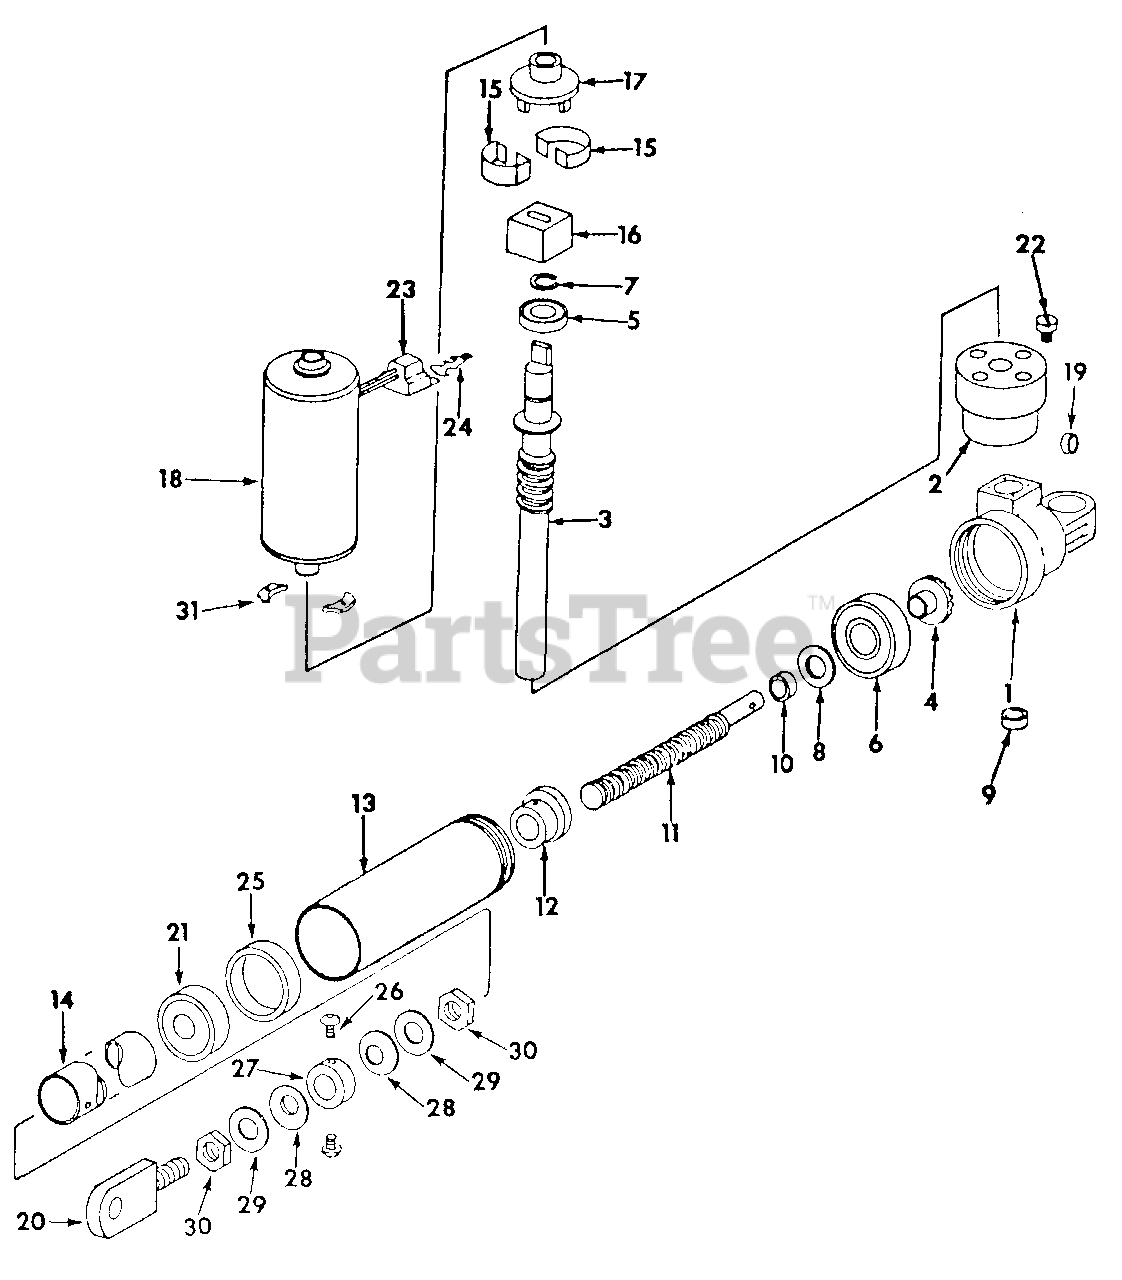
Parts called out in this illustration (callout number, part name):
2	Adapter, Motor
3	Pinion, Spiroid
4	Gear, Spiroid
5	Bearing, Pinion
6	Bearing, Load
7	Ring, Retaining
9	Bushing, Pinion
10	Bushing, Screw
12	Nut, Lifting
13	Tube, Outer
14	Tube, Translating
15	Spring, Brake
17	Coupling, Drive
18	Motor, Permanent Magnet
19	Bushing, Housing Clevis
20	Clevis Assy
22	Screw, Tap Tite
23	Connector, Multiple
25	Bushing, Guide
26	Not used in this application
27	Bushing
28	Washer, Belleville
29	Washer, Thrust
30	Nut, 1/2-20 Hex Lock
